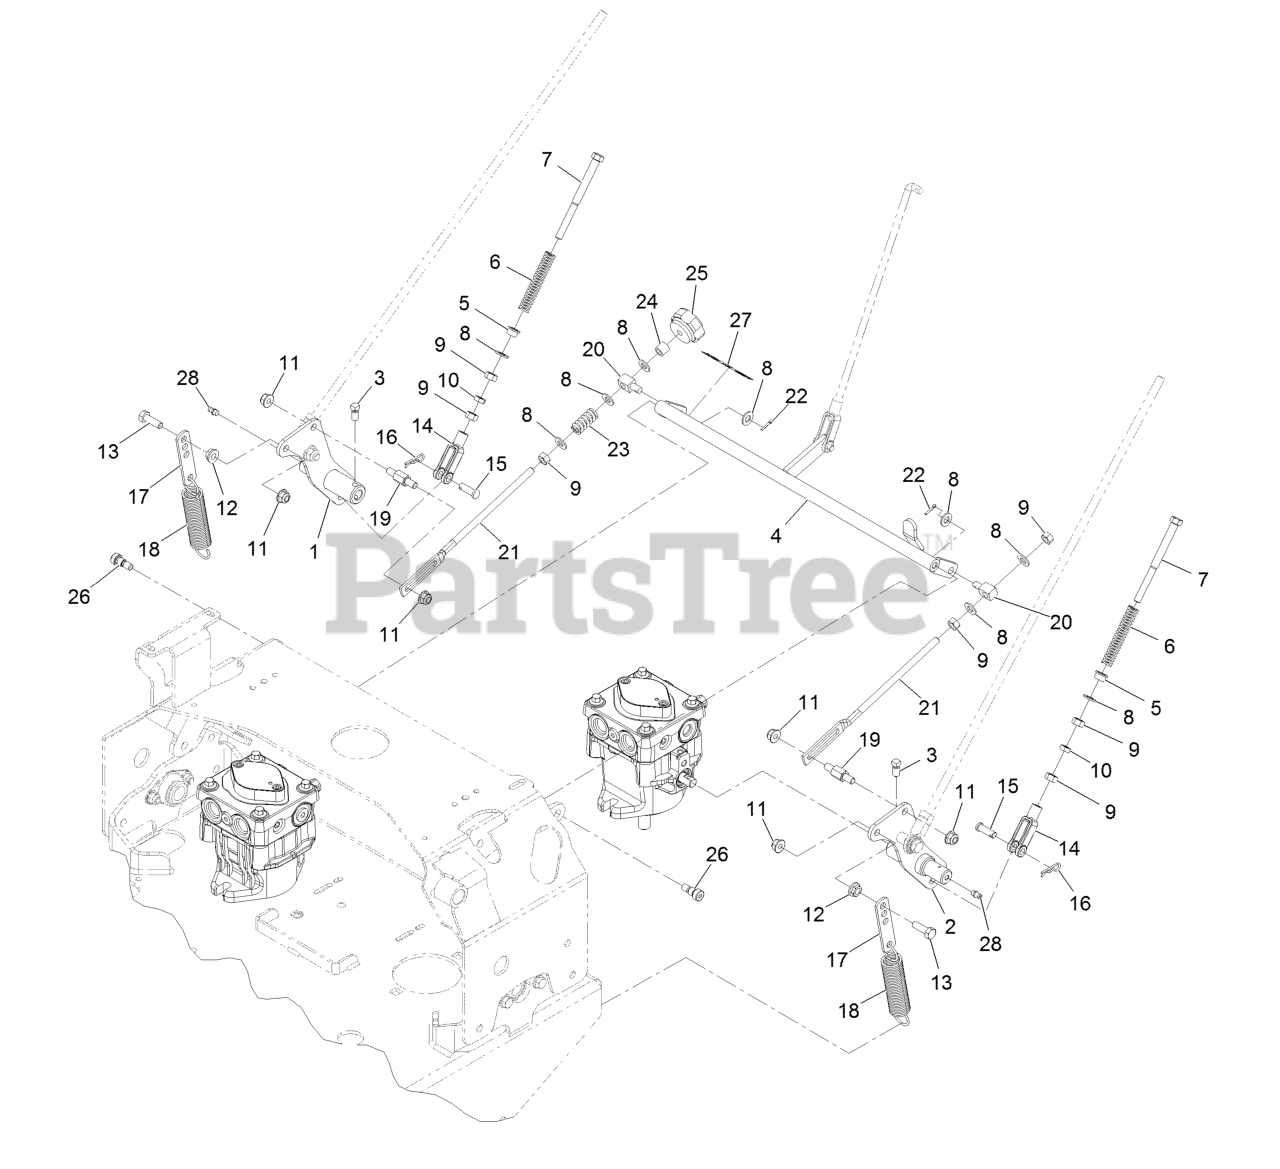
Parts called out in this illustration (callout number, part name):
1	Weld, Motion Control, Rt
2	Weld, Motion Control, Lt
3	Setscrew-5/16-18 X 5/8
4	Weld, Speed Control
5	Bushing-Flanged
6	Spring, Neutral Return
7	Bolt-Neutral Return
8	Washer-5/16 SAE
9	Nut-Hex 5/16-24
10	Nut-Jam 5/16-24
11	Nut-Nyloc 5/16-18 Flg
12	Nut-Whizlock 5/16-18
13	Screw-HH 5/16-18 X 1
14	Yoke-Adjustable
15	Pin-Clevis 5/16 X 1 49/64
16	Hairpin-Cotter
17	Tab-Spring, Extension
19	Pin, Motion Control
20	Swivel-Adjustable, Short
21	Link-Control, Speed
22	Pin-Cotter 3/32 X 1/2
23	Spring-Compression
25	Knob-Tracking
26	Screw-Sh 5/16-18 X 1 3/8
27	Decal-Tracking Adjustment
28	Zerk-1/4-28 Str
